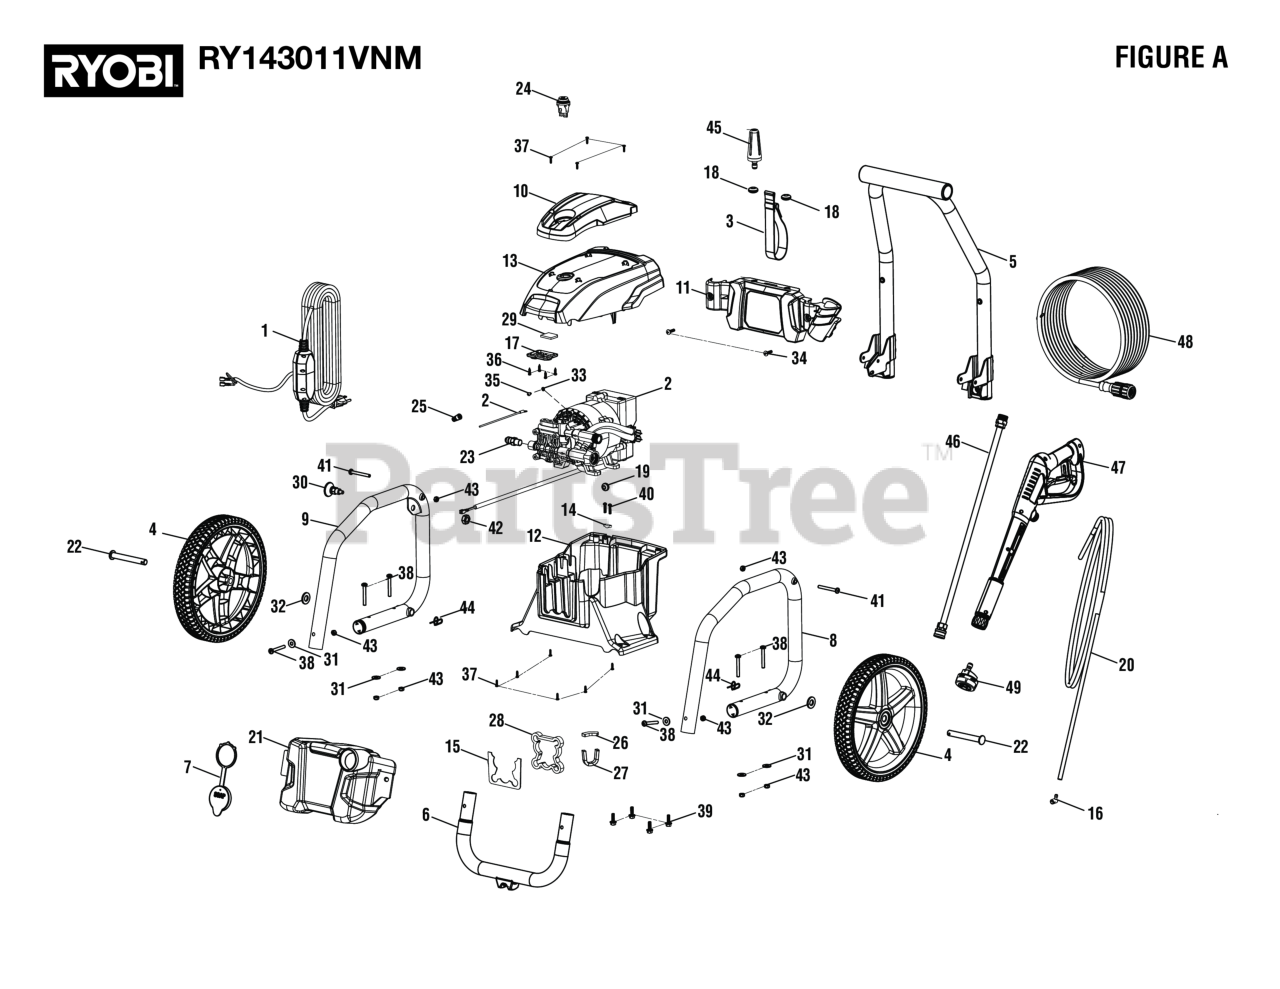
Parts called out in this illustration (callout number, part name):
1	Electrical Cord Grounded Assembly
2	Wire Contact Motor & Ground Electrode
3	Hose And Cord Strap
5	Handle Assembly
6	Front Frame Assembly
7	Detergent Tank Cap
8	Main Frame Assembly (Left)
9	Main Frame Assembly (Right)
10	Motor Shroud Cover
11	Performance Panel
12	Lower Housing
13	Motor Shroud
14	Electric Cord Clip
15	Pump Head Seal
16	Soap Hose Inlet Adapter
17	Switch Cover
18	Rubber Nozzle Grommet
19	Housing Rubber Grommet
20	Injection Hose
21	Detergent Tank
23	Thermal Release Valve.
24	On/Off Switch
25	Tuerca para alambre
26	Foam (39 mm)
27	Foam (85 mm)
28	Foam (352 mm)
29	Switch Cover Seal Foam
30	Handle Lock Assembly
31	Washer (1/4 in.)
32	Washer (1/2 in.)
33	Toothed Lock Washer (M4)
34	Bolt (M6 x 20 mm, Philips Pan Hd.)
35	Screw (M4 x 16 mm, Pan Hd.)
36	Screw (M2.9 x 14 mm, Pan Hd.)
37	Screw (ST 4.2 x 15mm, Pan Head)
38	Screw (M6 x 1 x 48 mm, T30 Torx Pan Hd.)
39	Bolt (M6 x 20 mm, Hex Hd. Locking)
40	Screw (M3.5 x 20 mm, Button Hd.)
41	Screw (M6 x 55 mm, T3 Torx Pan Hd.)
42	Lock Nut (1/2-20, Hex)
43	Lock Nut (M6 x 1)
44	Hitch Pin
45	Turbo Nozzle
46	Extension Wand
47	Trigger Handle (Inc. Key Nos. 61-64)
48	Hose (35 ft.)
49	5-N-1 Nozzle Assembly
